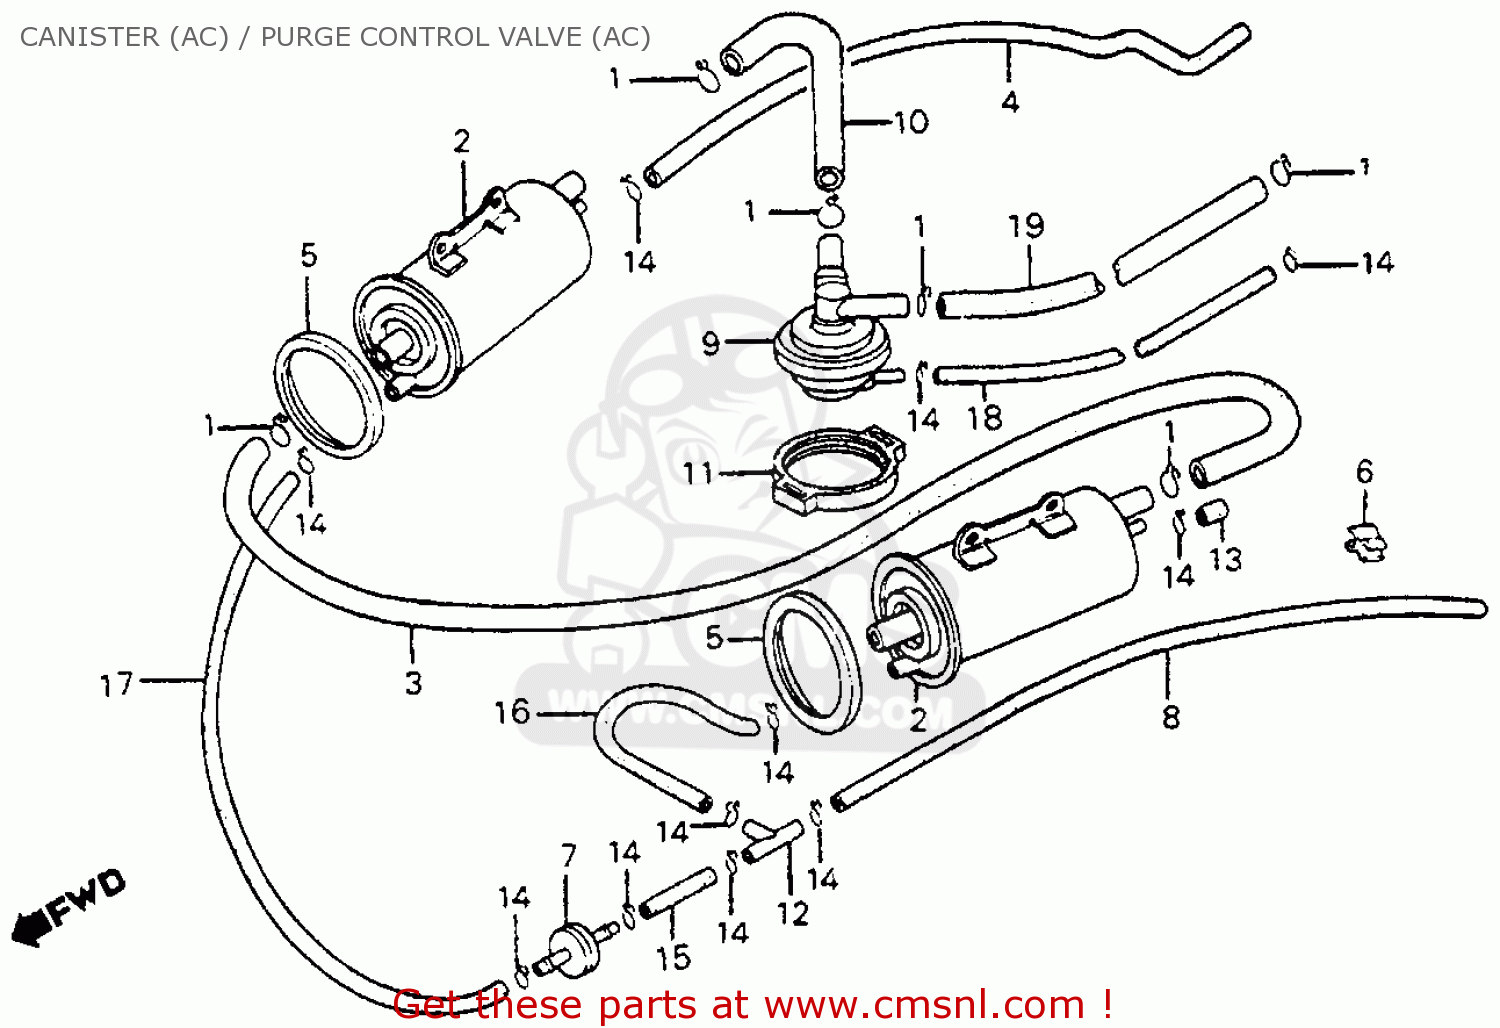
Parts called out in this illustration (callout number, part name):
1	CIR CLIP
2	CANISTER
3	TUBE, JOINT
4	TUBE, CHARGE
5	RUB, CANISTER GUARD
6	CLIP, TUBE
7	VALVE, ONE-WAY
8	TUBE, DRAIN
9	VALVE, PURGE CONTROL
10	TUBE, PURGE
11	SUSPENSION
12	JOINT,3 WAY
13	CAP, SEALING
14	CLIP B7,TUBE
15	BULK TUBE,TB 35X1
16	BULK TUBE,TB 35X1
17	BULK TUBE,TB 35X1
18	BULK TUBE,TB 35X1
19	BULK TUBE,TB 80X1
